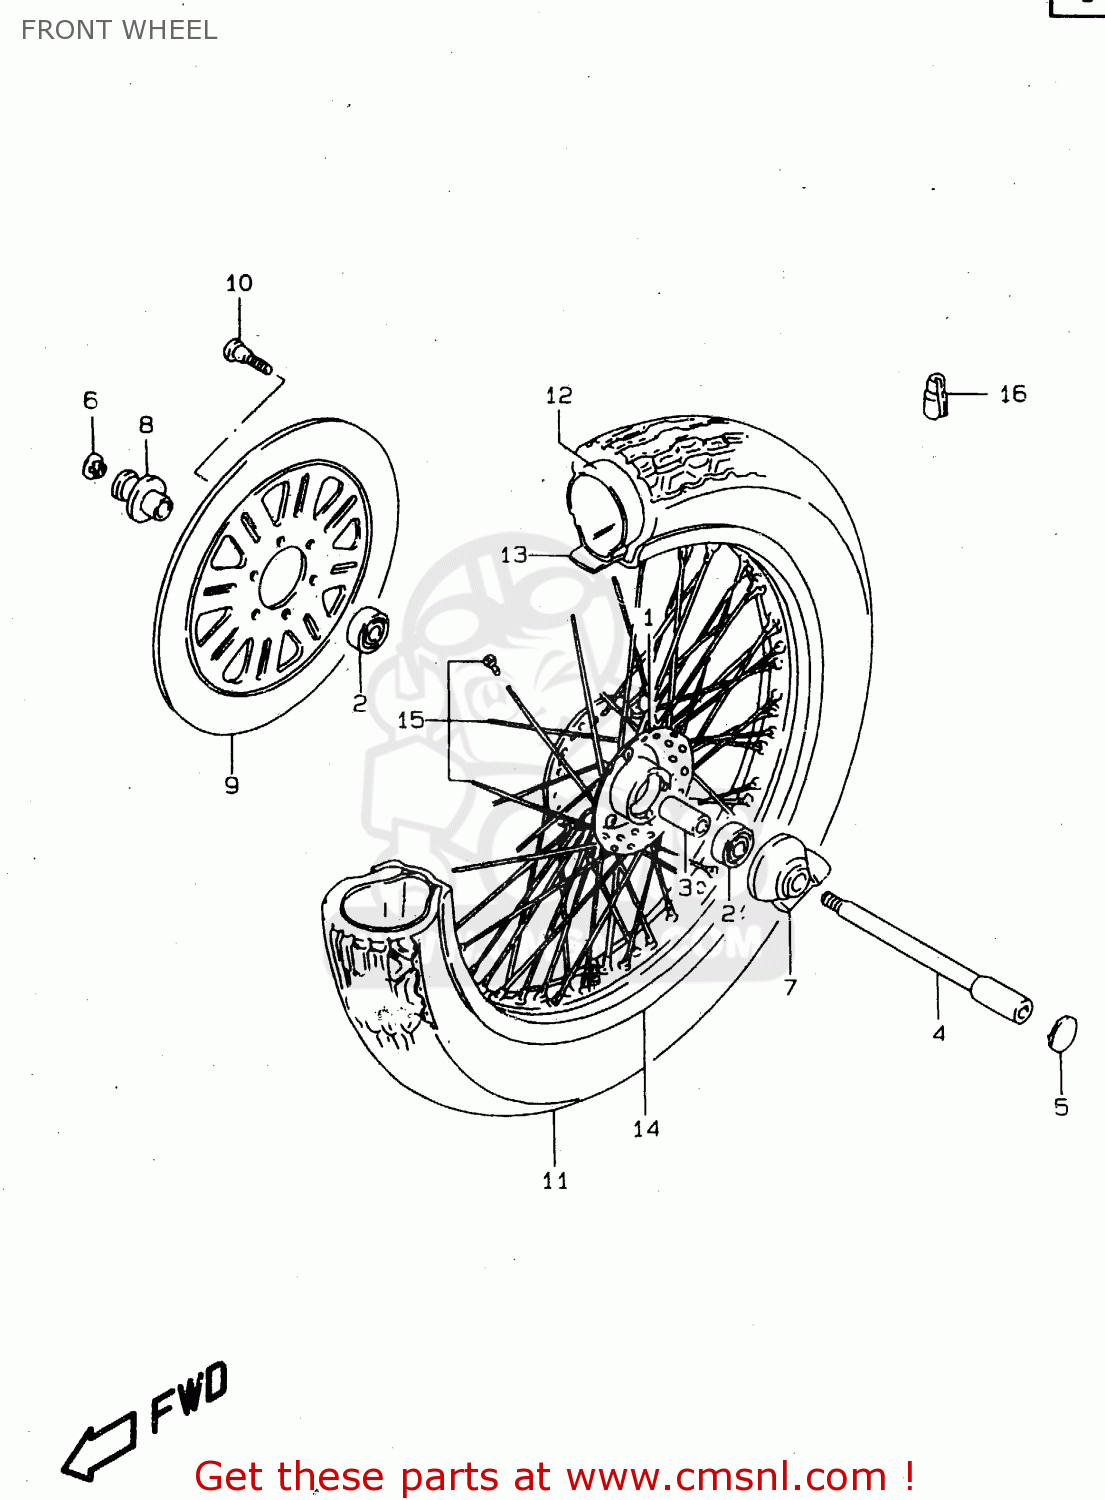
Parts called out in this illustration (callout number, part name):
1	HUB ASSY,FR
2	BEARING
3	SPACER(15.3X21.7X65)
4	AXLE,FR
5	CAP,FR AXLE
6	CAP,FR AXLE
7	BOX ASSY,SPEEDOMETER
8	SPACER,FR AXLE
9	DISC,FR BRAKE
10	BOLT 8X33
11	TIRE,FR(80/90 21 48H)
12	TUBE
13	PROTECTOR,WHEEL INNER
14	RIM,FR WHEEL(21X2.15 AL)
15	SPOKE SET,FR WHEEL
16	BALANCER,WHEEL
